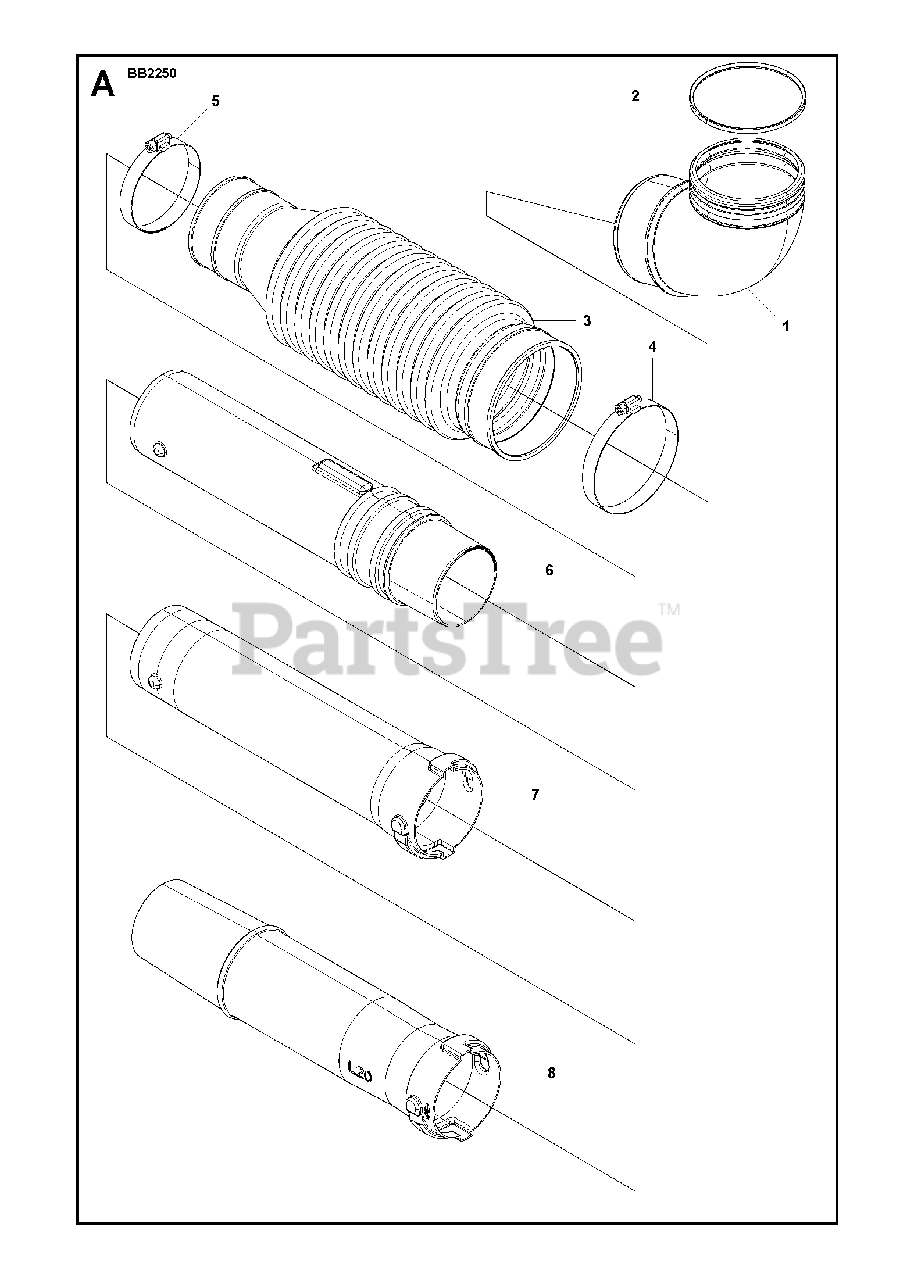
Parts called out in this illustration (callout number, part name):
1	PIPE BEND
3	RP_BELLOWS
4	CLAMP(F115)
6	SWIVEL JOINT
7	PIPE STRAIGHT
